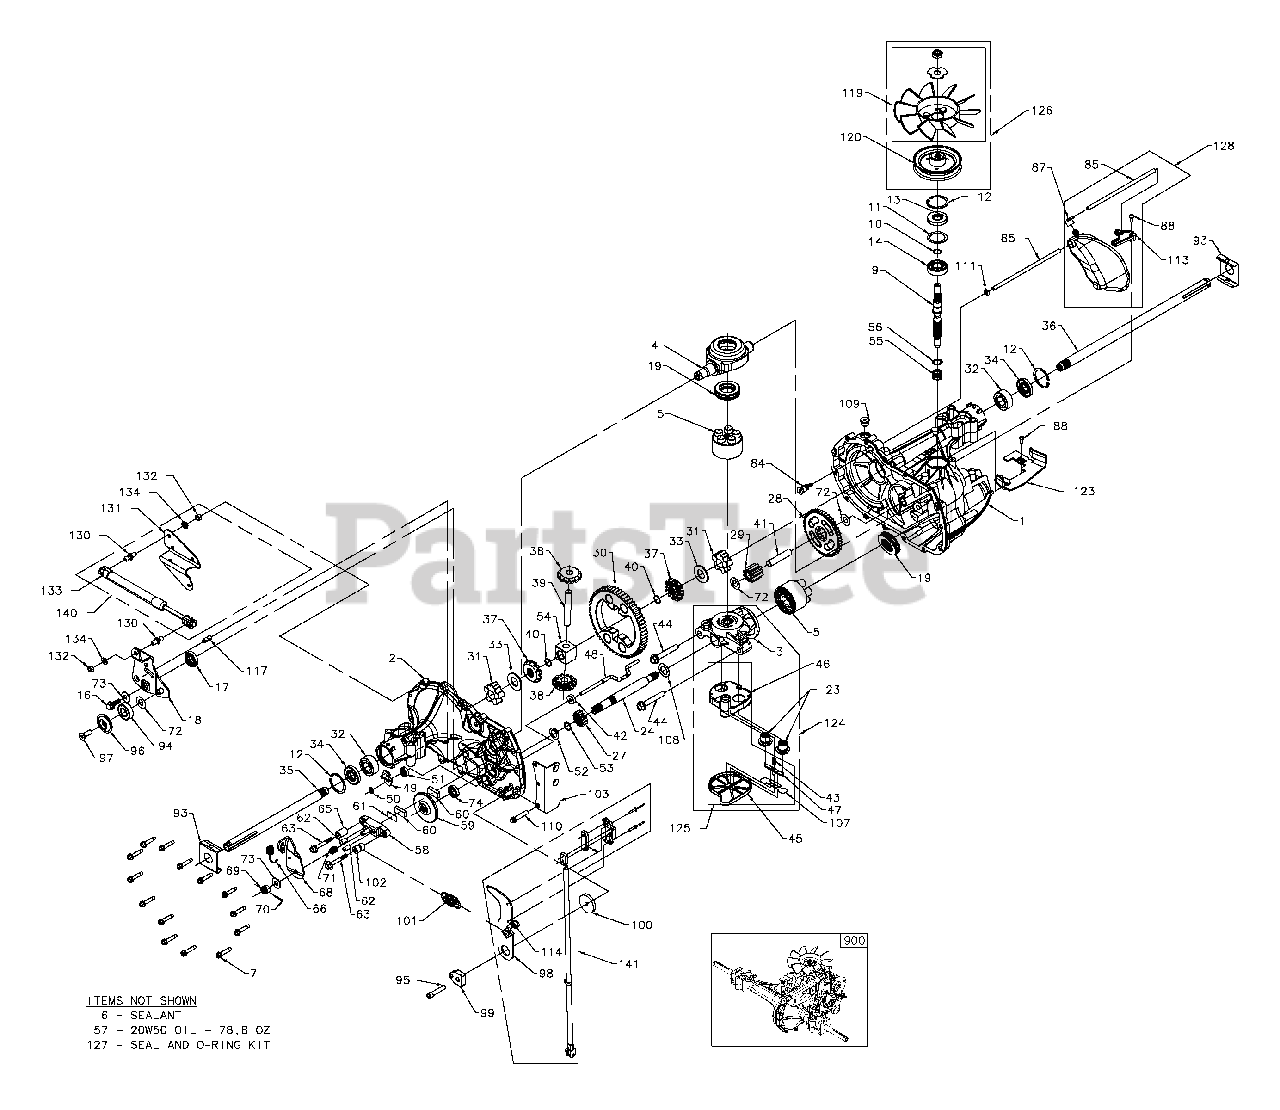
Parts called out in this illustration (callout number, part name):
1	Kit, Main Housing
1	Main Housing, Machined
2	Kit, Side Housing
2	Side Housing, Machined
3	Kit, Center Section
3	Center Section, Machined
4	Swashplate, Trunnion Machined
5	Kit, Cylinder Block (1000)
5	Block - Cylinder
5	Piston
5	Spring, Compression
5	Washer Thrust
6	Sealant Tube
7	Hex Flange Screw 1/4-20 X 1.25
9	Shaft, Input
10	Retaining Ring
11	Spacer
11	O-ring.07x.301 ID
12	Retaining Ring
13	Seal, Lip.67 X 1.58 X.276
14	Bearing, Ball 6203 (Bdr)
16	Hex Flange Head Screw 1/4-20 X 1.25
17	Seal, Lip 18 X 32 X 7
18	Arm, Control
19	Bearing, Thrust (10cc)
23	Check Plug Assembly, .027 Washer
24	Shaft Motor
27	Gear, Pinion, 13t
28	Gear 1 OT / 48t
29	Gear, 1 OT Jackshaft
30	60T Bullgear
31	Sleeve Bearing.75 X 1.75 X.625
32	Sleeve Bearing (Outboard).75 X 1.575 X.625
33	Washer
34	Lip Seal, Axle Shaft
35	Shaft, Axle (Keyed, R.H.)
36	Shaft, Axle (Keyed, L.H.)
37	Miter Gear (Splined)
38	Miter Gear
39	Differential Shaft (310-0750)
40	Retaining Ring
41	Pin, Jackshaft
42	Magnet, Ring
43	Spring, Bypass
44	Bolt 3/8-24 X 2-1/2
46	Base, Filter
47	Actuator, Bypass
48	Rod, Bypass Actuator
49	Arm, Bypass
50	Retaining Ring.25 External
51	Seal, Lip.741 X.25 X.25
52	Washer, Flat 0.050" (210-1000)
53	Retaining Ring
54	Bearing, Center Block
55	Spring, Helical Compression
56	Washer, Block Thrust
57	Oil
58	Kit, Brake Yoke
59	Rotor, Brake
60	Brake Puck
61	Brake Puck Plate
62	Pin, Brake Actuating
63	HFHCS 1/4-20 X 2 W/patch, Special Flange
65	Spacer, Brake Torsion Spring
66	Spring, Brake Arm Bias
68	Arm-brake, RH
69	Nut, Castle 5/16-24
70	Pin, Cotter 3/32x3/4
71	Brake Spring
72	Washer (310-0750)
73	Washer, Flat
74	Seal, Oil
84	Fitting, 5/16 X Sae 5/32 Tube
85	Hose, Expansion Tank
87	Cap, Barbed Vent
88	Bolt, Self Tapping (BDR)
93	Spring Clip, Housing
94	Bearing, Ball
95	Screw, 5/16-24x 1 1/2 Socket Head Cap (310-3000)
96	Spacer, Locating
97	Screw (310-3000)
98	Arm, Return
99	Puck, Adjusting
100	Washer, .325 OD xl.6 Idx.15 Tk
101	Spring, Extension
102	Spacer, .56 ODx.26 ID X.87
103	Bracket, Torque
107	Deflector
108	Washer, Motor Shaft.71 Id X 1.150d X .03 Thick
109	Plug, Straight Thread 9/16-18
110	Screw, Torx Head 5/16-18 (310-3000)
111	O-ring .7 X .301 ID
113	Bracket, Support Expansion Tank
114	Spring Guide
117	Pin, Spring 5/16 X.75
119	Kit, Fan - Washer - Nut
119	Fan, 7 In
119	Hex Lock Nut 1/2-20 (Nylon Insert) Washer
120	Pulley
123	Belt Keeper
124	Center Section Filter Bypass Assembly
124	Center Section
124	Base Filter W/ Poppet
124	Check Plug Assembly,.027 Washer Spring
124	Bypass Actuator,
124	Bypass Deflector Bottom,
125	Kit, Filter
125	Bottom, Filter Spring,
125	Bypass Actuator,
125	Bypass Deflector
125	Base, Filter W/ Poppet
126	Kit, Fan/pulley
126	Hex Jam 1/20-20 (Nylon Inser) Washer
126	Fan, 7 In
126	Pulley
127	Kit, Seal
127	Lip Seal.741 X.250 X.250 TC
128	Kit, Expansion Tank
128	Tank,
128	Expansion Assembly Cap,
128	Barbed Vent
128	Bracket, Support Expansion
128	Tank Hose,
128	Expansion Tank
130	Stud, Threaded Ball
131	Bracket, Cruise/Damper
132	Nut 5/16-18
133	Damper
134	Washer, 5/16 Lock
140	Kit, Damper
140	Stud, Threaded Ball Bracket,
140	Cruise/Damper
140	Hex Nut 5/16-18 NC Damper
140	Washer, Helical Spring Lock 5/16, Regular
141	Kit, Lt Rcs
141	Arm, Return
141	Spring Guide
141	Switch, RCS Activator,
141	RCS Switch Spring,
141	RCS Switch Retainer,
900	Transaxle Assembly-Complete
